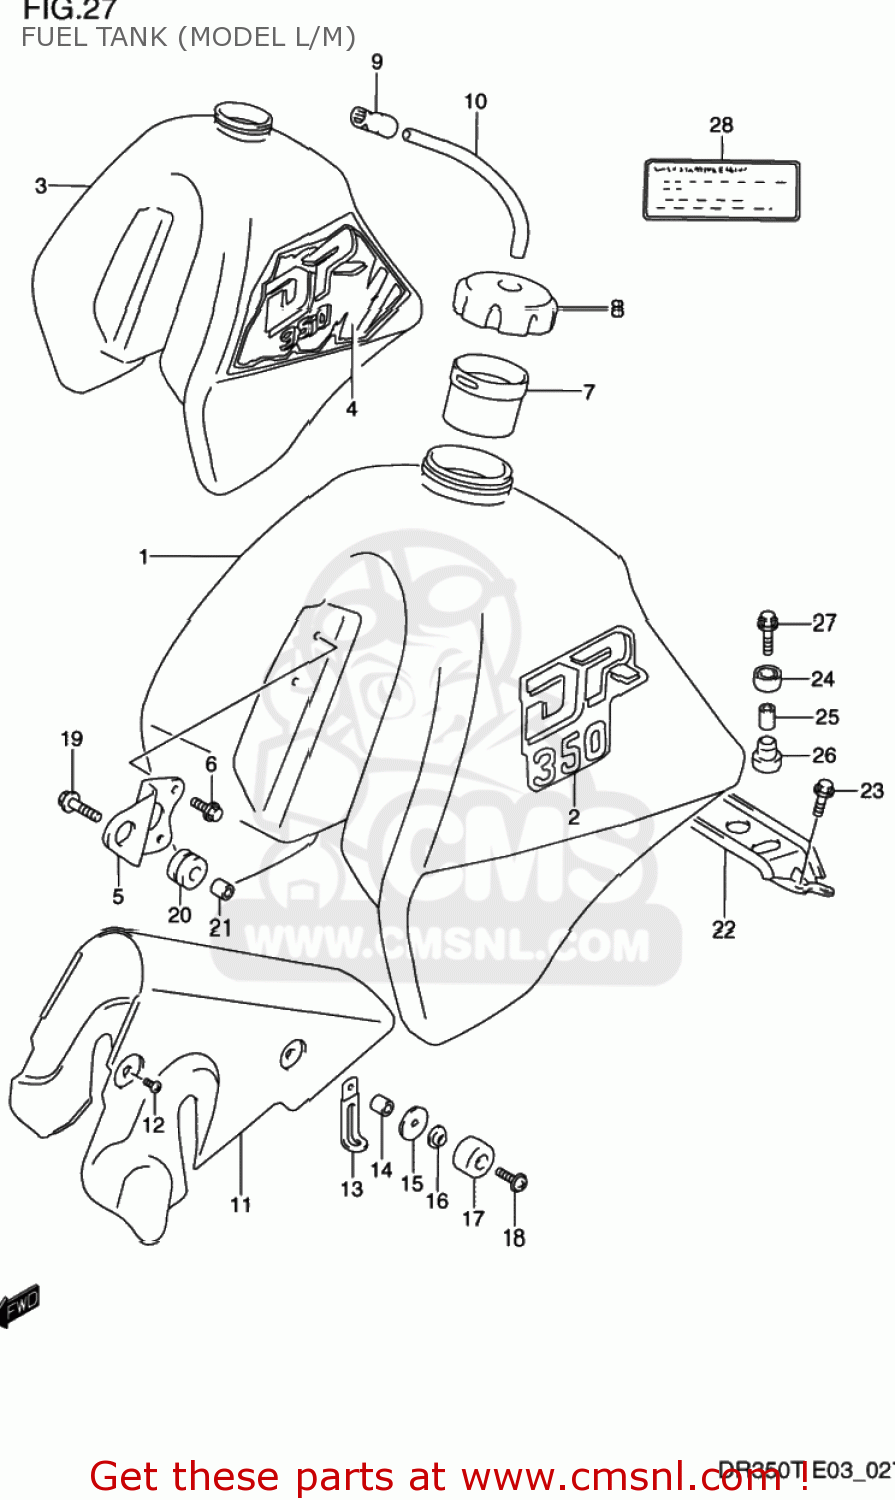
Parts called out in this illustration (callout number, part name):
1	TANK ASSEMBLY,FUEL
2	EMBLEM
3	TANK ASSEMBLY,FUEL
4	TAPE SET,FUEL TANK
5	BRACKET,FUEL TANK,FRONT
6	BOLT
7	TUBE,FILLER INLET
8	CAP ASSY,FUEL TANK
9	CLAMP,FUEL TANK BREATHER HOSE
10	HOSE(5X8.2X600)
11	HEAT SHIELD,FUEL TANK
12	SCREW
13	CLAMP
14	SPACER(6.1X14X7.2)
15	WASHER (6.5X26X2.3)
16	WASHER
17	CUSHION
18	SCREW
19	BOLT(8X25)
20	CUSHION
21	SPACER (8.8X12X12.5)
22	BRACKET,FUEL TANK RR
23	BOLT
24	CUSHION
25	SPACER
26	CUSHION
27	BOLT
28	LABEL,STARTING CAUTION
